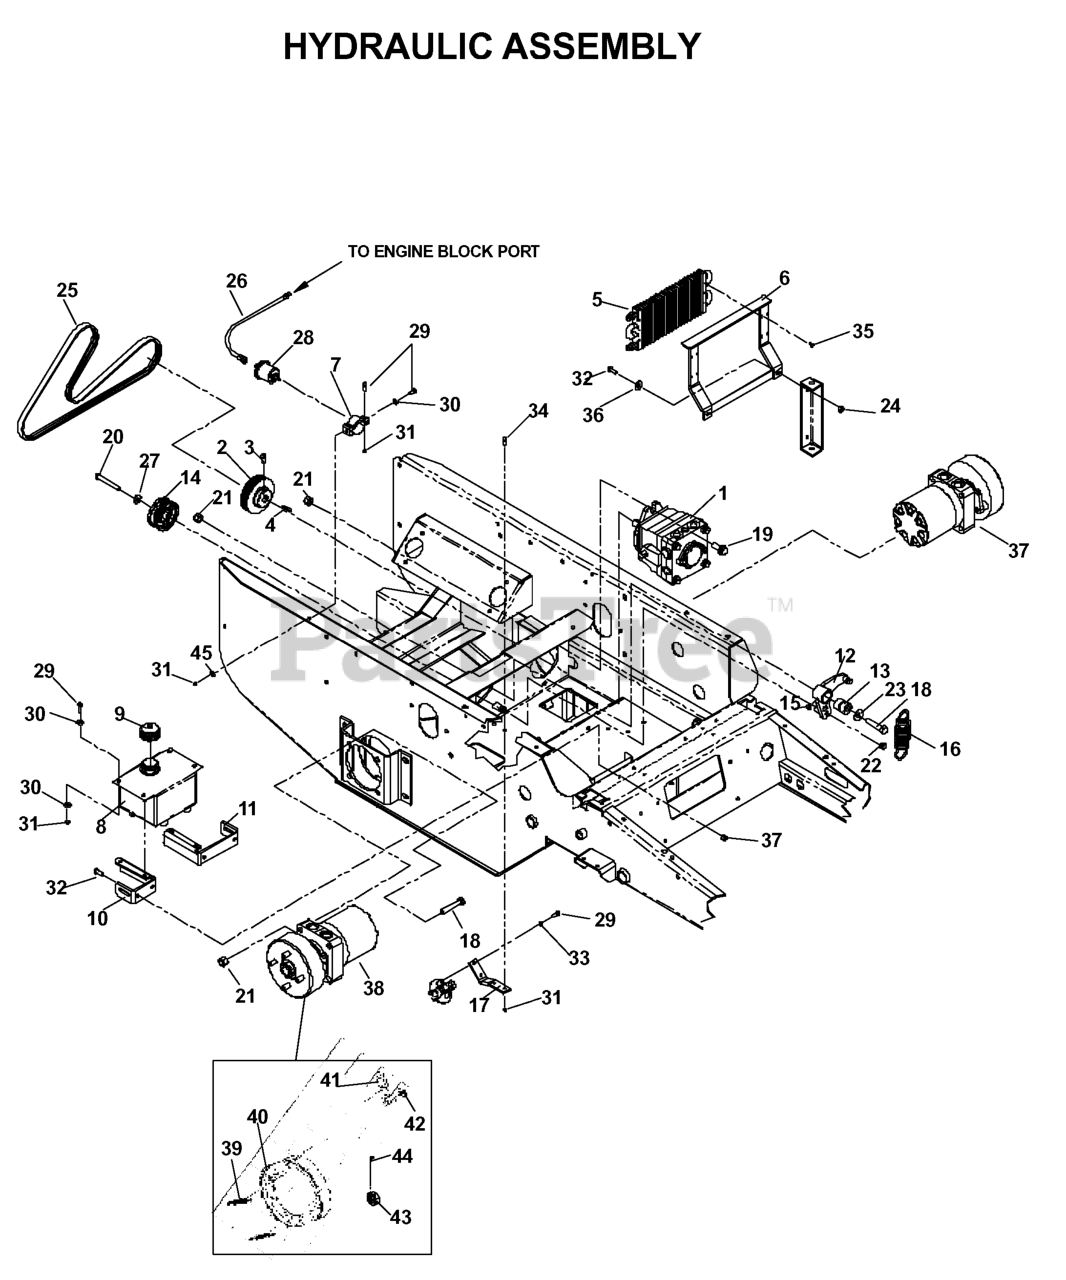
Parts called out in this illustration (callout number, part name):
1	HG_PUMP CCW RH
2	PUMP SHEAVE
3	SCREW 5/16C X 1 SQ HEAD SET
4	KEY, METRIC
6	COOLER WLDMT MT
7	CLAMP-OIL SENDER
8	TANK, OIL = PAINTED
9	HYDRAULIC CAP
10	TANK MOUNT RT
11	TANK MOUNT LT
12	ARM WELDMENT
14	IDLER PULLEY
17	FILTER MOUNT - PAINTED
18	HEX SCREW 1/2-13 X 2.5" GR 5
19	HCS 1/2C X 1 1/4 SERRATED HEAD
20	HCS 3/8C X 3
21	NUT 1/2-13 HEX NYLOC ZD
22	NUT 3/8-16 NYLOC
23	WASHER 1/2 FLAT
24	NUT 5/16 NYLOC
27	WASHER 3/8 SAE FLAT
28	SENDER,OIL PRESS
29	HCS 1/4C X 3/4 HCS
30	WASHER 1/4 FLAT
31	NUT.1/4-20.HEX.NYLOC.ZD
32	HCS 5/16C X 1
33	LOCKWASHER 1/4"
34	HCS 1/4 X 1
35	HSMS #10 X 5/8
36	WASHER 5/16 FLAT
37	WHEEL MTR ASM
38	WHEEL MTR ASM, RT
39	RETURN SPRING
43	CASTLE-NUT
44	COTTER PIN
45	WASHER 1/4 EXTLW STAR ZD
